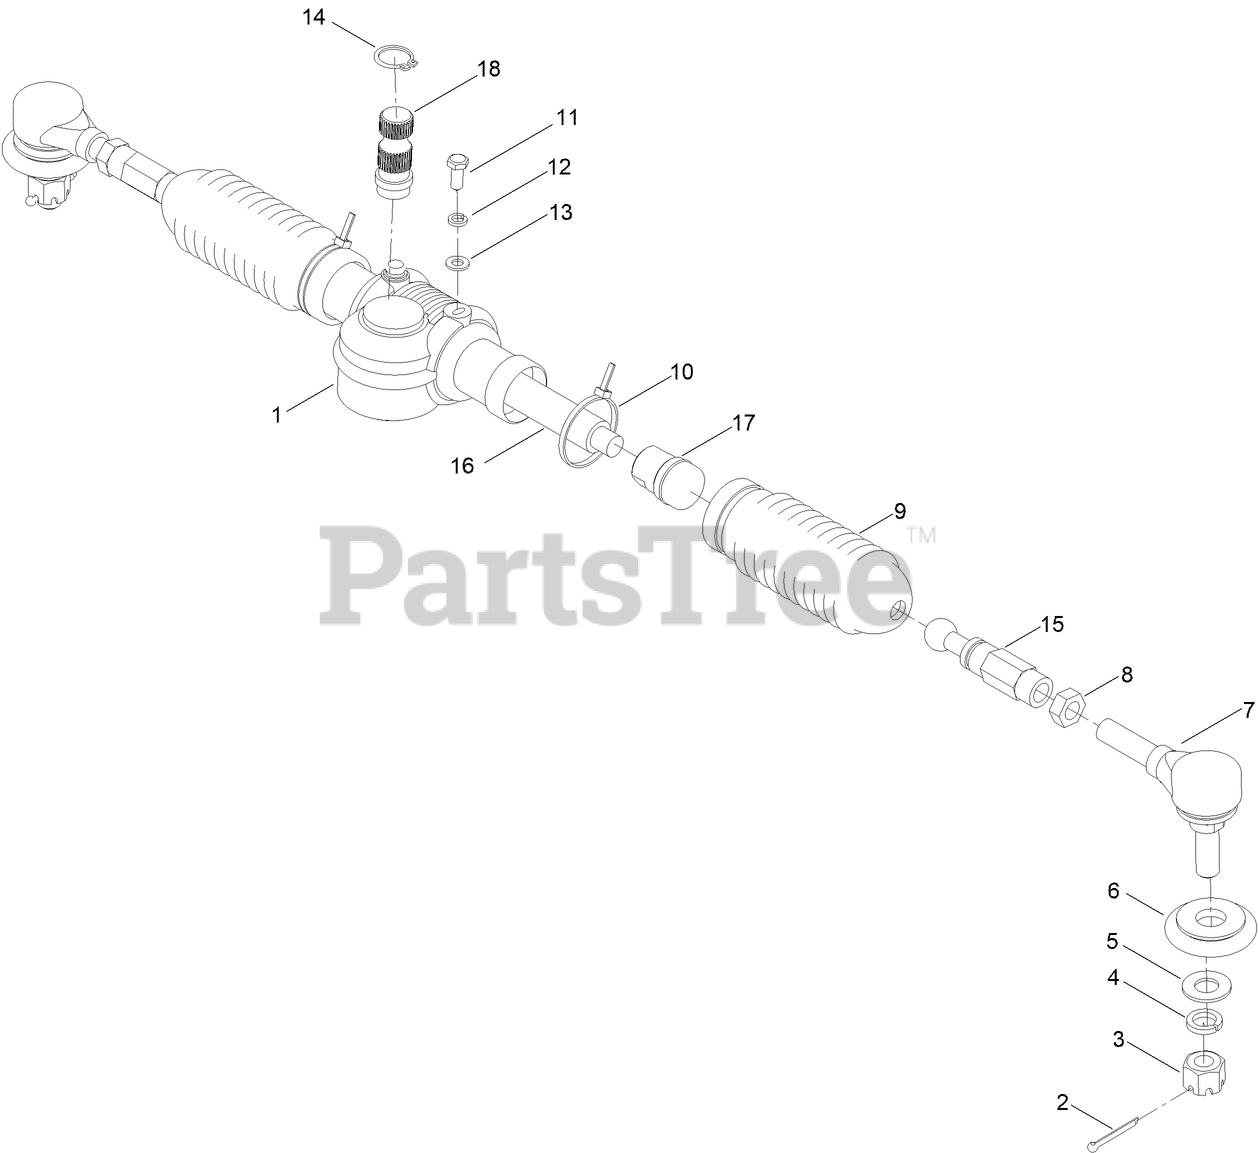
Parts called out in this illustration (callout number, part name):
1	STEERING RACK
4	WASHER-LOCK
5	WASHER-PLAIN
6	COVER, MOUNTING (STEERING RACK)
7	CONNECTION, STEERING
8	NUT, ADJUSTMENT
9	COVER, STEERING COVER
10	ZIPTIE
11	SCREW-HH
12	WASHER-SPRING
13	WASHER
14	CLIP, STEERING RACK
15	CON, TIE ROD
16	TIE ROD, MAIN
17	END, TIE ROD
18	SHAFT, STEERING RACK
